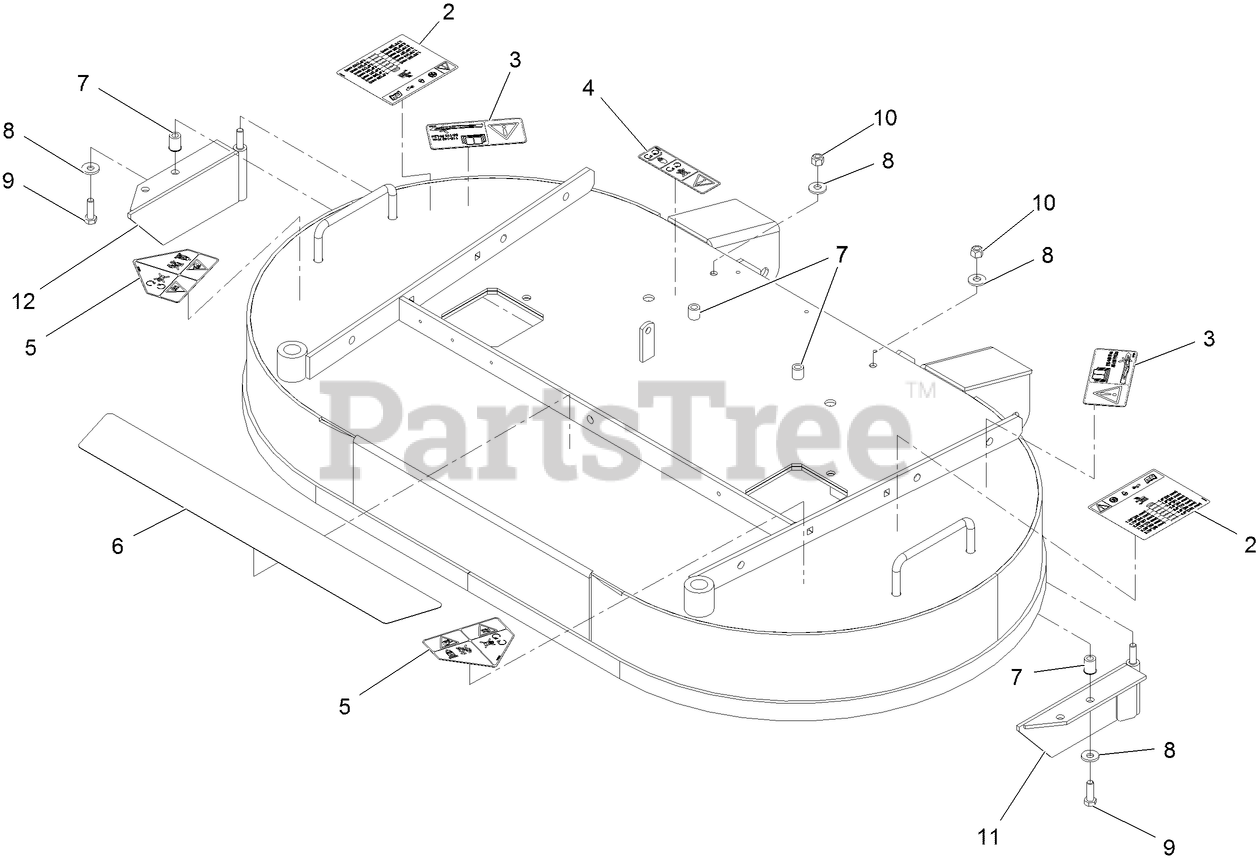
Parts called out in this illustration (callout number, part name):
2	DECAL-HEIGHT ADJUST, CUTT
3	DECAL-TORQUE, BLADE BOLT
4	DECAL-COVER, MISSING
5	DECAL-DANGER
6	PAD-SKID, ANTI
7	NUT-CLINCH
8	WASHER-SPRING
9	SCREW-HH
10	NUT-LOCK, NI
11	BAFFLE-LH
12	BAFFLE-RH
